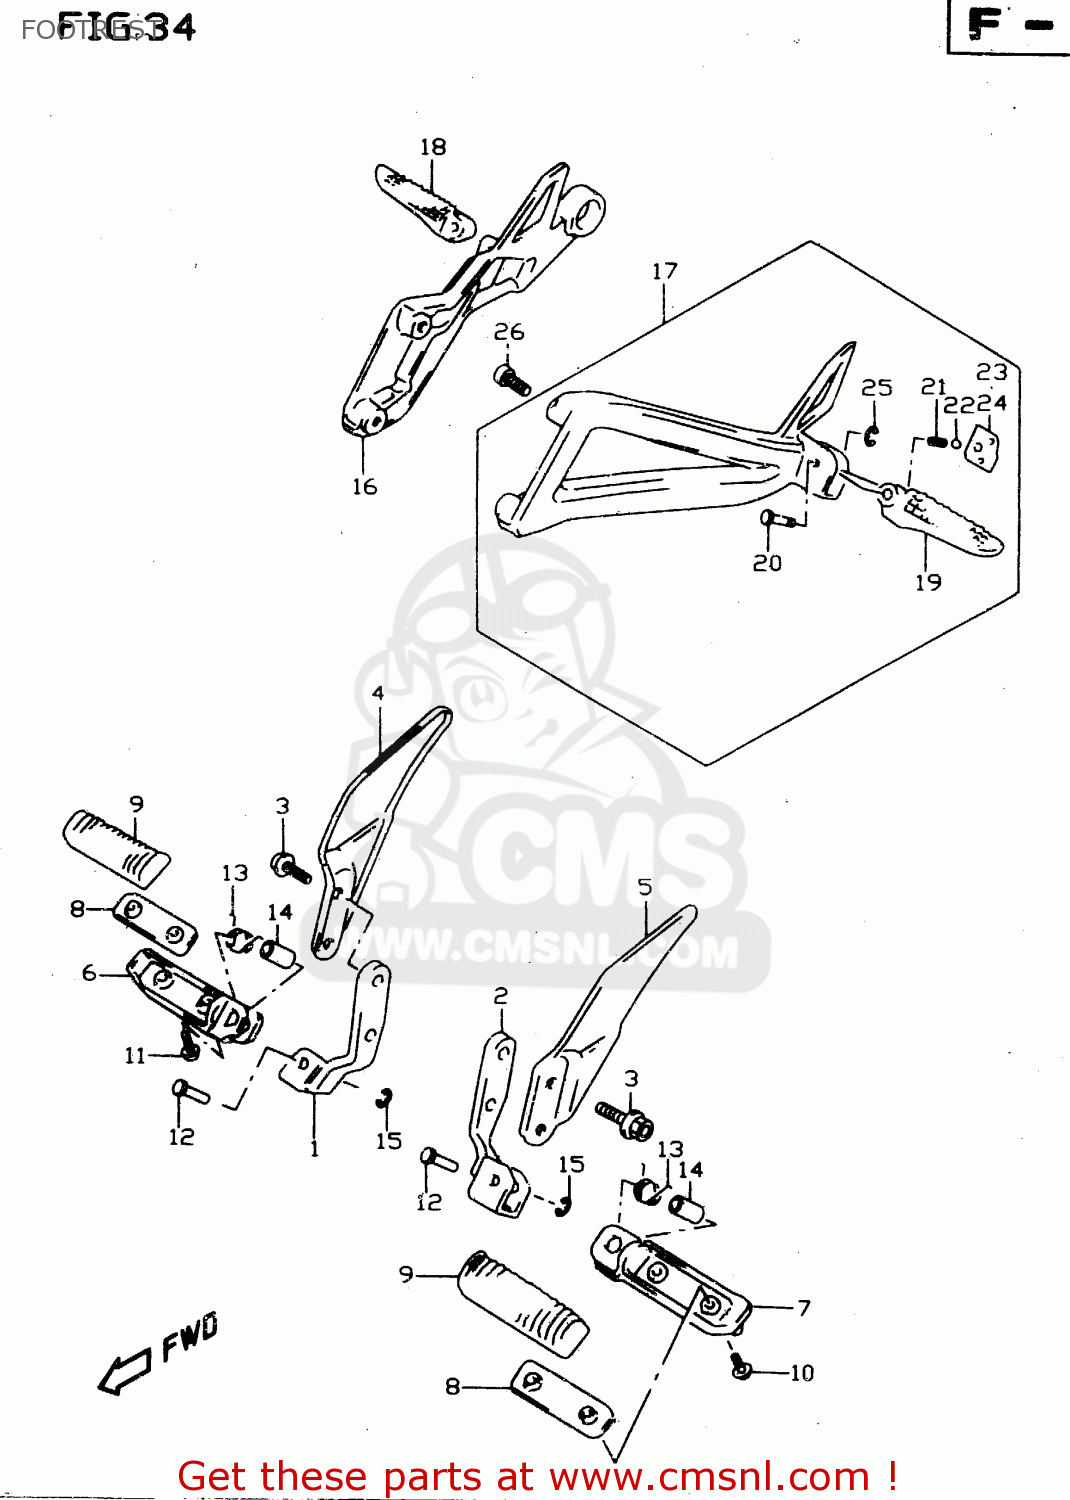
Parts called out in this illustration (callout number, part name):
1	HOLDER,FR FOOTREST,R
2	HOLDER,FR FOOTREST,L
3	BOLT(10X24)
4	GUARD,FR FOOTREST,R
5	GUARD,FR FOOTREST,L
6	BAR,FOOTREST,R
7	BAR,FOOTREST,L
8	BALANCER,FR FOOTREST UPR
9	RUBBER,FOOTREST
10	SCREW 5X20
11	SCREW
12	PIN(8X33.2)
13	SPRING
14	SPACER(8.1X12X22)
15	E.RING
16	FOOTREST,PILLION
17	FOOTREST,PILLI
18	BAR,PILLION FOOTREST,RIGHT
19	BAR,PILLION FOOTREST,LEFT
20	PIN
21	SPRING
22	BALL
23	PLATE,PILLION,RIGHT
24	PLATE,PILLION,LEFT
25	E-RING
26	BOLT
